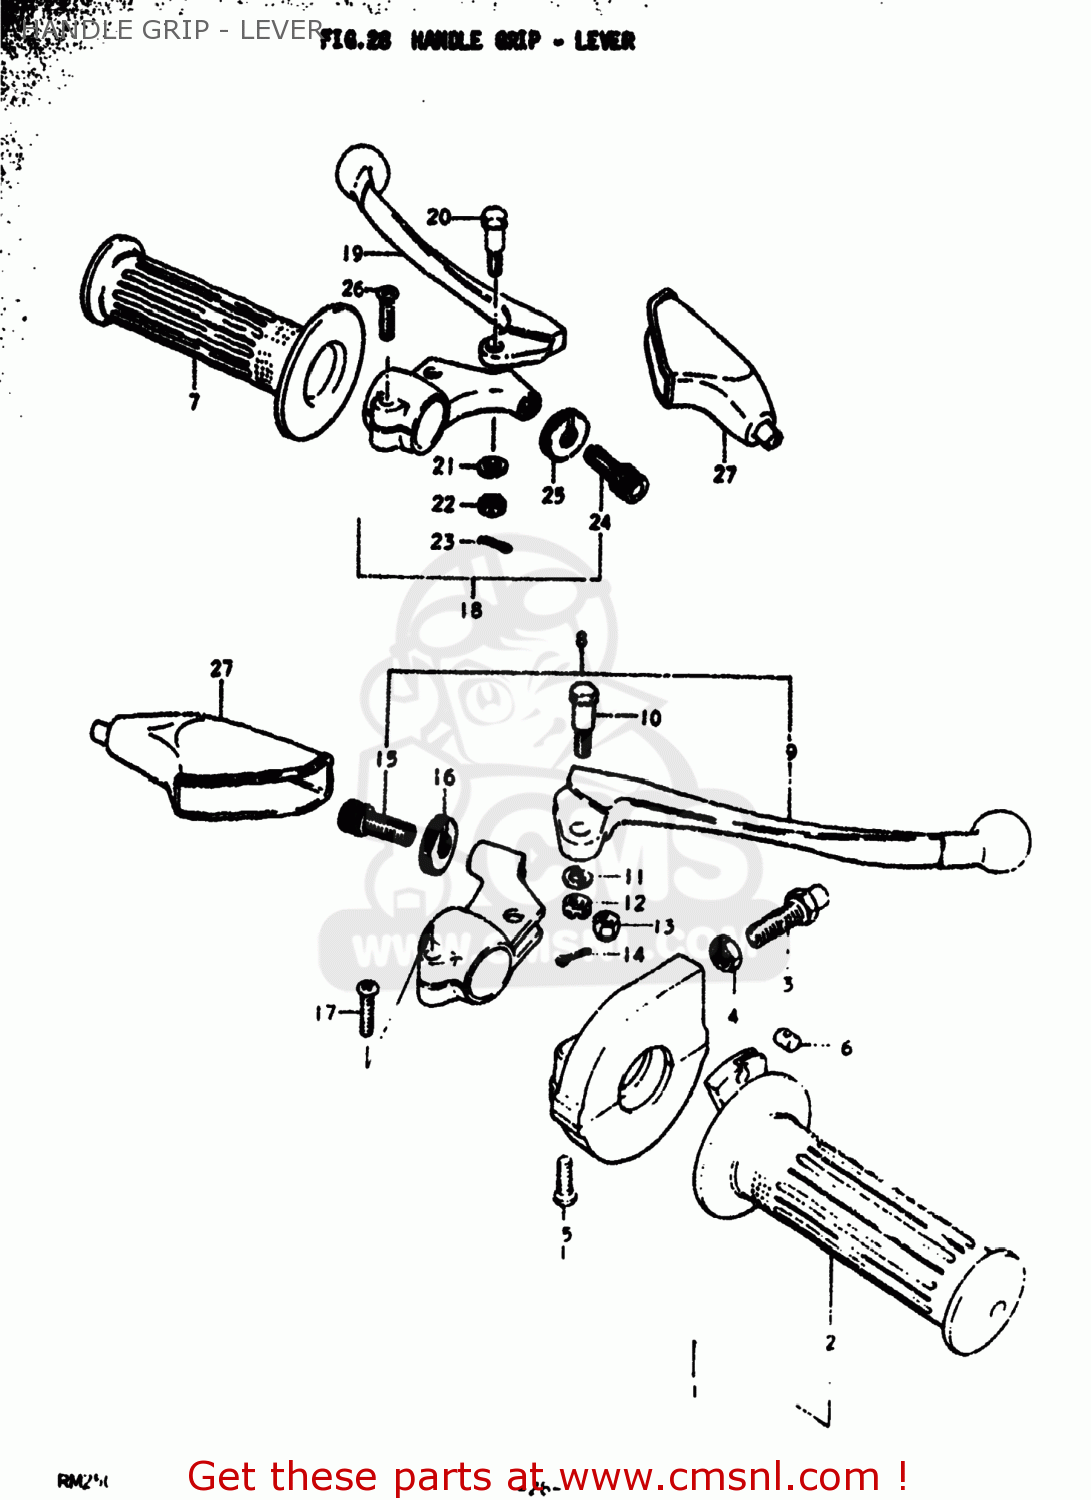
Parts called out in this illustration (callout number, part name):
1	GRIP ASSY,THROTTLE
2	GRIP,THROTTLE
4	NUT
5	SCREW
6	PIECE,THROTTLE END
7	GRIP,LEFT
8	LEVER ASSEMBLY,BRAKE
9	LEVER,BRAKE
10	BOLT,LEVER
11	LOCK WASHER
12	NUT,LEVER FITTNG
13	NUT 6MM
14	COTTER PIN
15	ADJUSTER,CABLE
16	NUT,CABLE ADJUSTER
17	SCREW
18	LEVER ASSEMBLY
19	LEVER,CLUTCH
20	BOLT,LEVER
21	LOCK WASHER
22	NUT,LEVER FITTNG
23	COTTER PIN
24	ADJUSTER,CABLE
25	NUT,CABLE ADJUSTER
26	SCREW
27	COVER,CLUTCH LEVER
